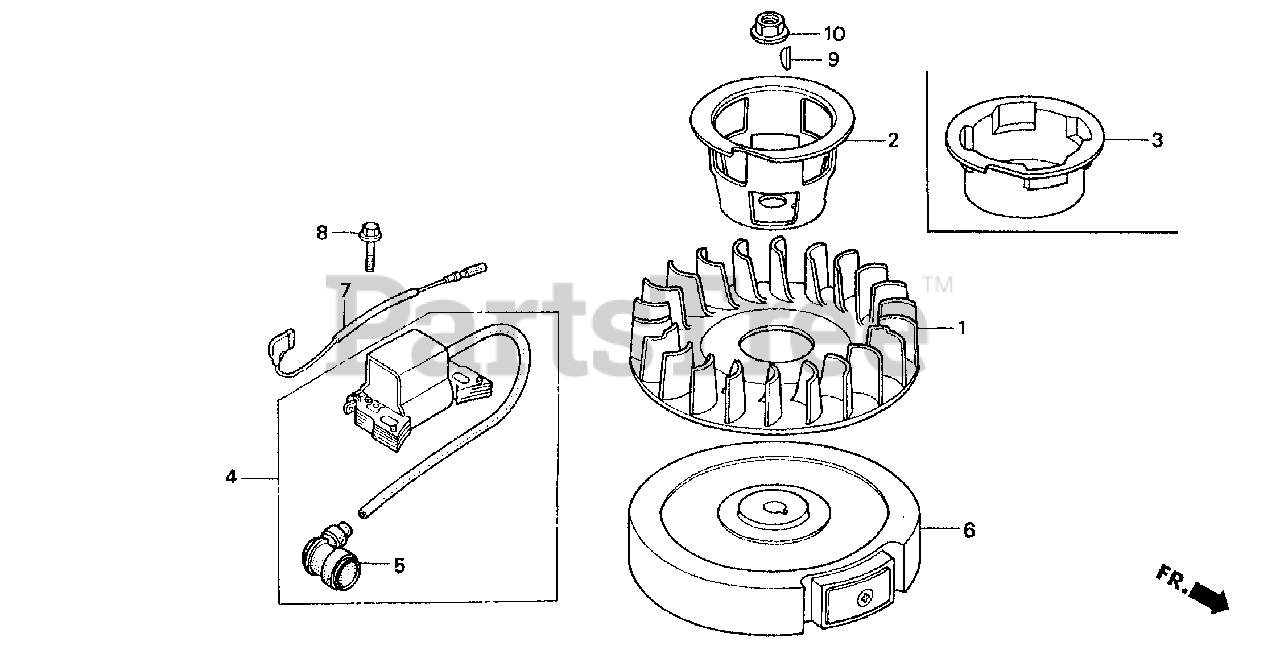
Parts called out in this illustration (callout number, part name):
1	FAN, COOLING
3	PULLEY, STARTER
4	COIL ASSY., IGNITION
5	CAP ASSY., NOISE SUPPRESSOR
6	FLYWHEEL
7	WIRE, STOP SWITCH (200MM)
8	BOLT, FLANGE (6X25)
9	KEY, WOODRUFF (3MM)
10	NUT, FLANGE (12MM)
